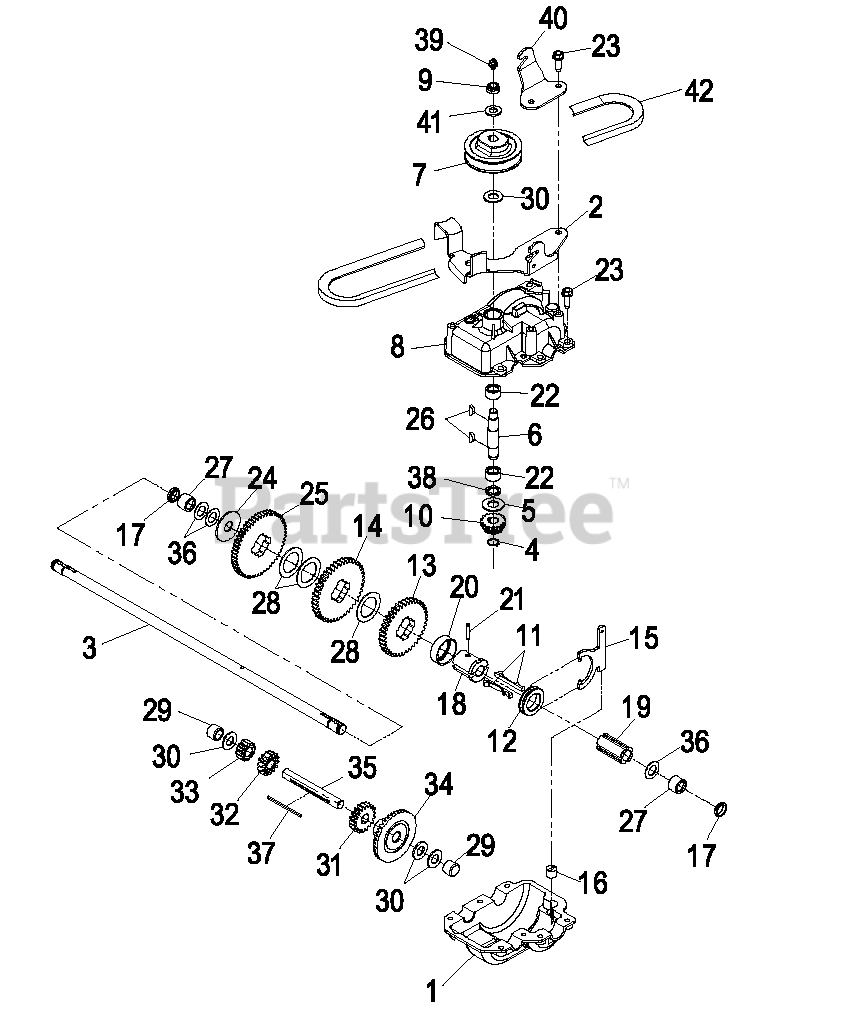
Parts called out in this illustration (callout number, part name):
2	BRACKET-GUIDE, BELT
3	SHAFT-OUTPUT
4	RING-RETAINING
5	WASHER-THRUST
9	NUT-HEX
10	PINION-BEVEL
11	KEY-SHIFT
12	COLLAR-SHIFT
13	GEAR-38T
14	GEAR-42T
15	YOKE-SHIFT
16	BUSHING-YOKE
17	SEAL-OIL
18	SLEEVE-GEAR
20	RETAINER-KEY
21	PIN-GROOVE
22	BEARING-NEEDLE
23	SCREW-HWHTF
26	KEY-WOODRUFF
29	BEARING-NEEDLE, CLOSED
30	WASHER-THRUST
31	GEAR-18T
32	GEAR-14T
33	GEAR-12T
34	GEAR-BEVEL
35	SHAFT-INTERMEDIATE
36	WASHER-PLAIN
39	FITTING-GREASE, ZERK
40	BRACKET-ENGAGE, TRACTION
41	WASHER-FLAT
42	V-BELT
